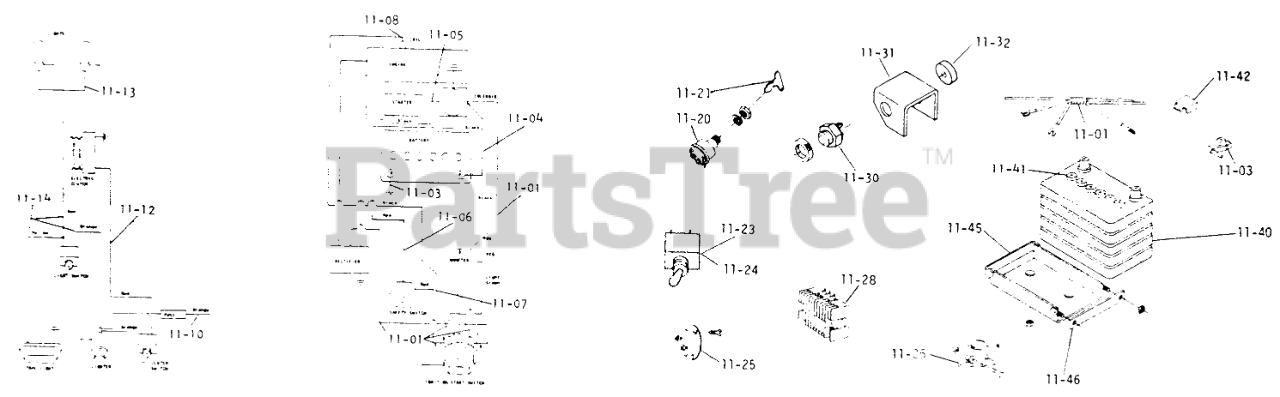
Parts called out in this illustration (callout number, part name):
11-01	Harness-Wiring (Main)
11-02	Grommet
11-04	WIRE SOLENOID
11-05	Wire
11-06	WIRE ASSY
11-07	Wire Assy.
11-08	Wire Assy.-Coil to Harness
11-10	ASSY FUSED CONN
11-12	Wire-Clutch
11-13	WIRE ASSY
11-14	Harness-Headlights
11-20	Switch-Ignition
11-21	Key-EL
11-23	SWITCH-LIGHTS
11-24	SWITCH-LIGHTS
11-25	AMMETER W/CLAMP
11-26	Solenoid
11-28	REGULATOR-RECTIFIER
11-30	SWITCH SAFETY
11-31	Bracket
11-32	WASHER
11-40	Battery
11-42	Cover Battery Term
11-45	BATTERY BOX ASSY R (NS)
11-46	LINK BATTERY CLAMP
